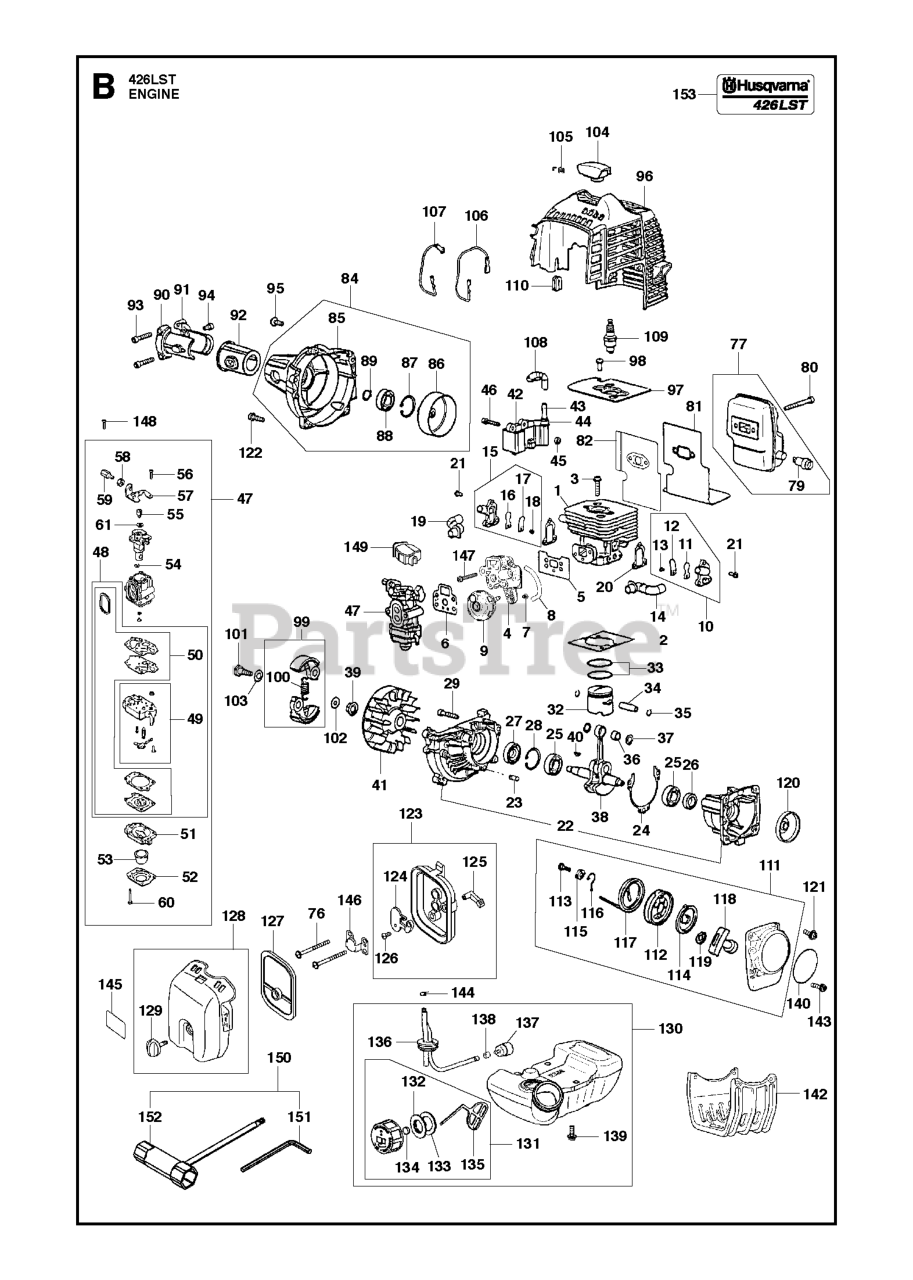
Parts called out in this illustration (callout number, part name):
2	GASKET, BASE
5	GASKET, INSULATOR
6	GASKET, CARB (RPLS T155113131)
10	AIR CHECKER (S) ASSY
14	PIPE AIR (S)
15	AIR CHECKER (F) ASSY
19	PIPE AIR (F)
20	GASKET, VALVE
22	CRANKCASE-C
24	GASKET.CASE
25	BEARING
34	PIN (RPLS T151341310)
38	CRANKSHAFT COMP(RPLS481042000)
39	NUT
44	CAP
47	CARBURETOR WYA-138
48	REBUILD KIT
49	CARBURETOR BODY
50	GASKET KIT
58	NUT
59	SCREW CABLE ADJUST
82	PLATE, MUFFLER
84	COVER COMP
90	BRACKET(A)-24
91	BRACKET(B)-24
96	COVER ENGINE
98	BOLT 08
107	CORD.EARTH
108	TUBE (RPLS 263072210)
109	SPARK PLUG NGK CMR7H
114	SPRING, SPIRAL
119	PLATE.STOPPER
121	BOLT M5X14
124	PLATE, CHOKE
127	ELEMENT
128	COVER ASSY
130	TANK-A
136	PIPE-C
137	FILTER
140	LABEL RECOIL
150	TOOL SET (RPLS 848-8UD-0120)
152	SOCKET
